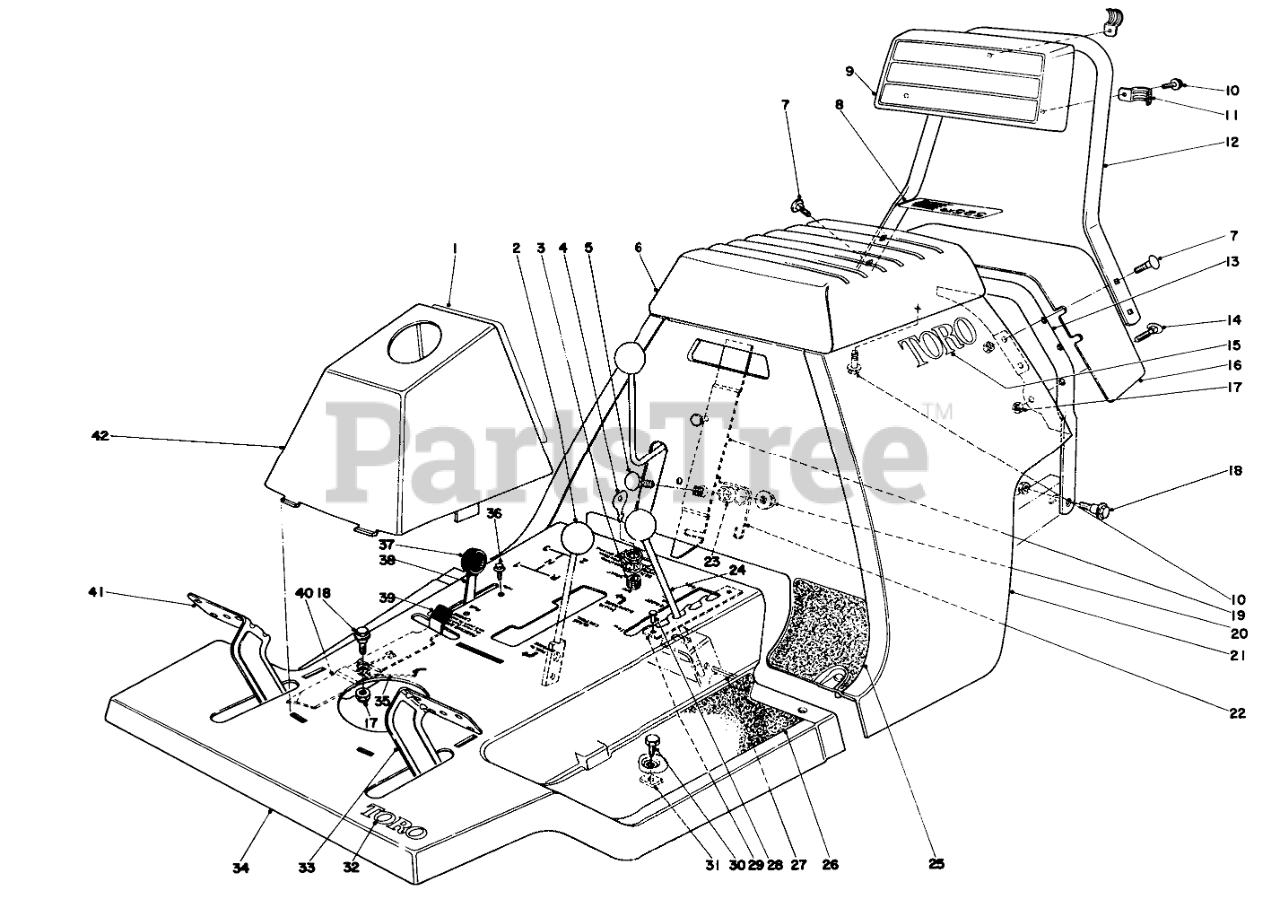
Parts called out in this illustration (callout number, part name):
1	Decal Tower
2	KNOB-CONTROL
3	ON-OFF SWITCH 21-8-468
4	Key
5	BOLT-CARR
7	SCREW-CARR
8	Spring-Shoe Return, R.H.
9	Backrest
10	SCREW-HHF
11	CLAMP-CONDUIT
12	Handle Upper
13	Handle Lower
14	HANDLE SCREW
15	Decal
16	Extension-Rear Body
17	NUT-LOCK, CONE
18	SCREW-SHOULDER
19	Handle Latch
20	NUT-HF
21	Rear Body
22	Latch Return Spring
23	Spacer
24	Height of Cut Lever
25	Heel Pad L.H.
26	Foot Tread L.H.
27	PIN-SPRING
29	Height Adjustment Plate
30	SCREW-HH
31	NUT-TINNERMAN
32	DECAL
33	Clutch Pedal
34	Front Body (Incl. Ref. #28 & 29)
35	SPRING-PARKING BRAKE
36	8X1/2 SELF TAP SCREW
38	Throttle Control (Incl. Ref. #37)
39	TIP-PARKING BRAKE
40	Parking Brake
41	Brake Pedal
42	Tower
